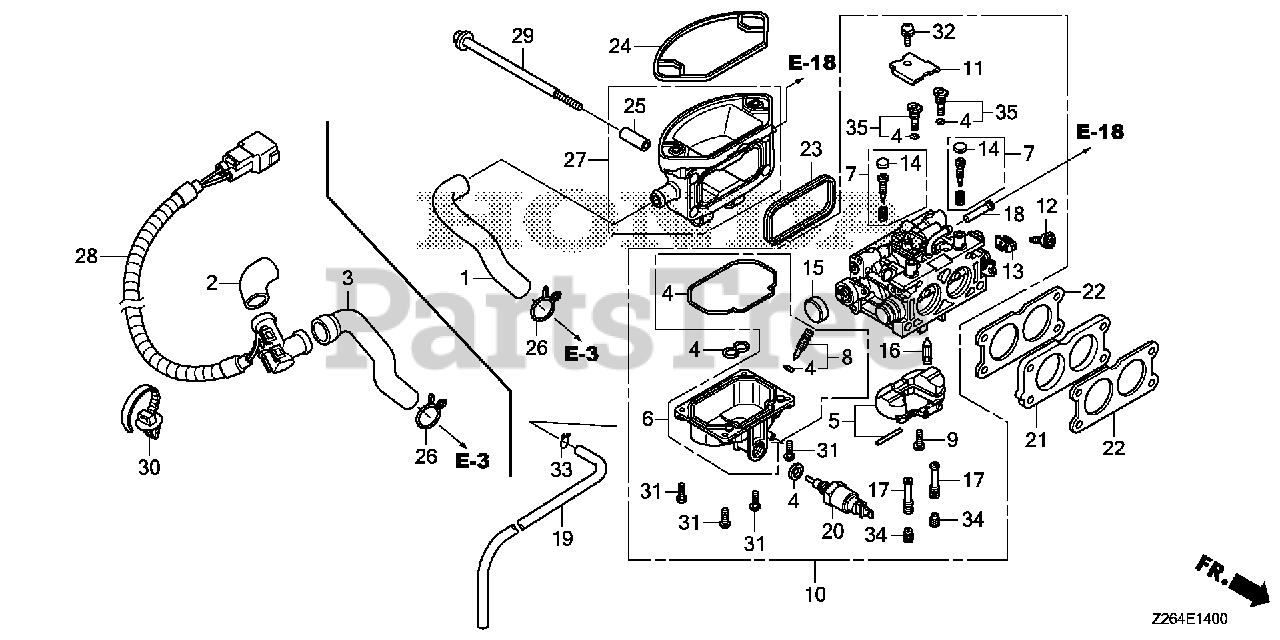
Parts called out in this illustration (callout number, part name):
1	TUBE, BREATHER
4	GASKET SET
6	CHAMBER SET, FLOAT
8	SCREW SET, DRAIN
9	SCREW, FLOAT
10	CARBURETOR ASSY. (BK07L D)
12	SCREW, THROTTLE STOP
13	ARM, THROTTLE LINKAGE
14	CAP, ADJUSTING SCREW
15	CAP, CHOKE DUST
16	VALVE, FLOAT
17	NOZZLE, MAIN
18	SCREEN, FUEL STRAINER
19	TUBE, DRAIN
20	VALVE ASSY., SOLENOID
21	INSULATOR, CARBURETOR
22	GASKET, CARBURETOR
23	GASKET, AIR CLEANER
24	SEAL, AIR CLEANER HOUSING
25	COLLAR, AIR CLEANER
26	CLIP, BREATHER TUBE
27	ELBOW, AIR CLEANER
29	BOLT, FLANGE (6X106)
31	SCREW, PAN (4X12)
32	SCREW-WASHER (5X10)
33	CLIP, TUBE (B8)
34	JET, MAIN (#98)
34	JET, MAIN (#102)
34	JET, MAIN (#110)
35	JET SET, PILOT (#40)
